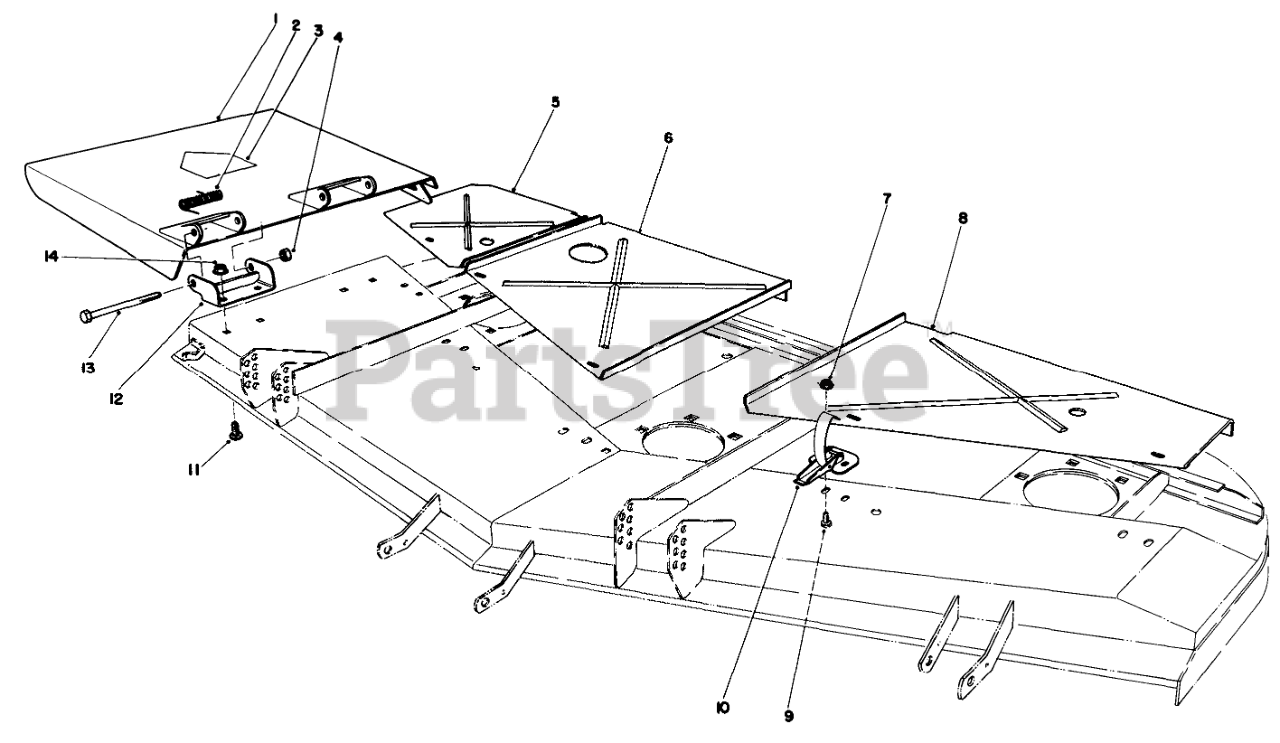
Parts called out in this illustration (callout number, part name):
1	Deflector
2	SPRING
3	DECAL-DANGER
4	NUT-HEX
5	Cover-Deck R.H.
6	CTR DECK COVER R
7	NUT-LOCK, FLANGE
8	Cover-Deck L.H.
9	SCREW-HWH
10	CLAMP-SLOTTED
11	SCREW-CARR
12	Bracket-Hinge
13	SCREW-HH
14	NUT-HHF, WHIZ
